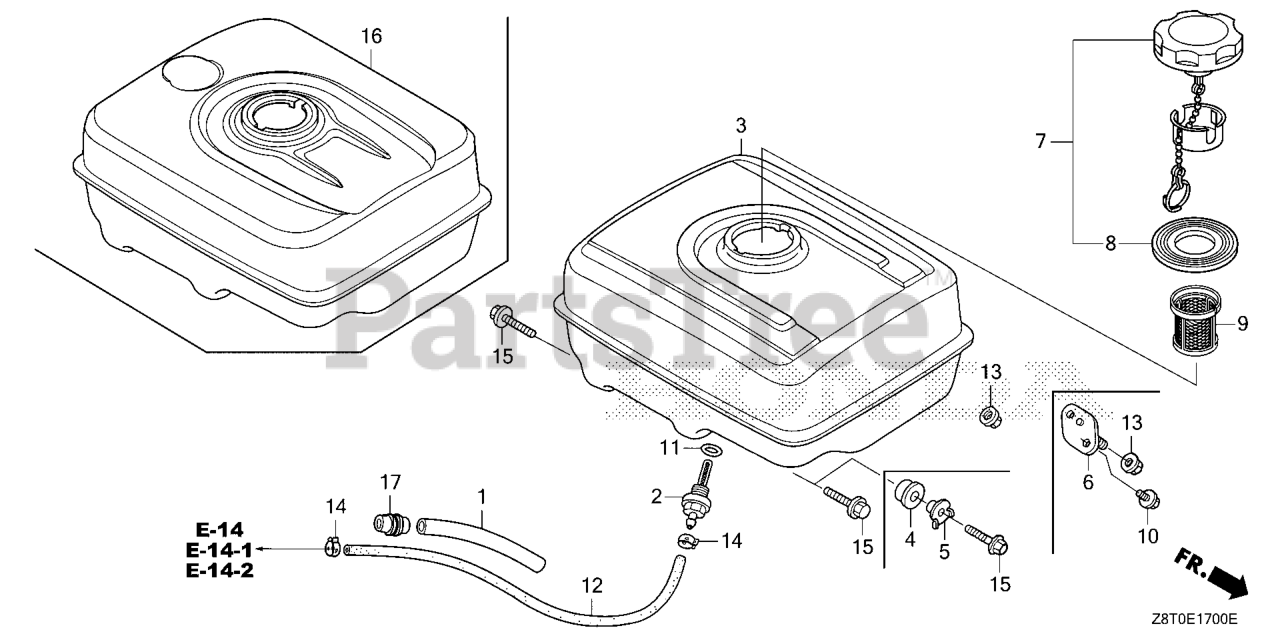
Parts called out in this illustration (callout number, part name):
1	RUBBER, SUPPORTER (107MM)
2	JOINT, FUEL TANK
7	CAP, FUEL FILLER
8	GASKET, FUEL FILLER CAP
9	FILTER, FUEL (FROM 1204807)
11	O-RING (14MM) (ARAI) Use up to Engine SN 2949254.
12	TUBE, FUEL (4.5X235) (FKM)
13	NUT, FLANGE (8MM)
14	CLIP, TUBE (D8)
15	BOLT, FLANGE (8X25)
16	TANK, FUEL *NH1* (BLACK)
16	TANK, FUEL *NH31* (MCKINLEY WHITE)
